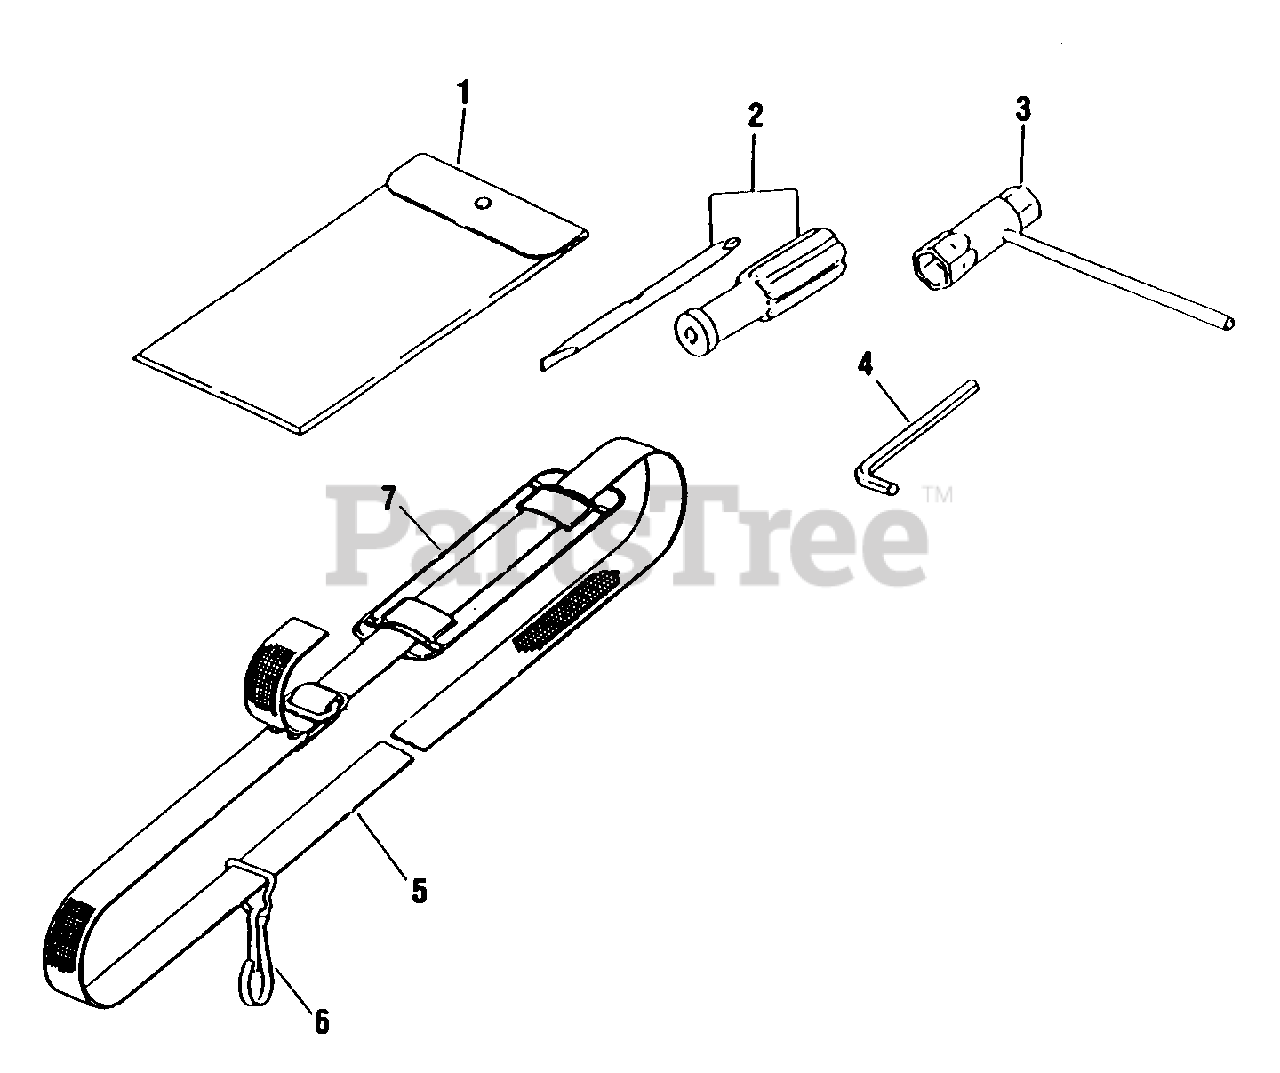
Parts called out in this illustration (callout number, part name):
1	BAG, TOOL
2	SCREWDRIVER
3	T-WRENCH 13×19 MM
4	WRENCH - 4
5	BELT
7	PROTECTOR
